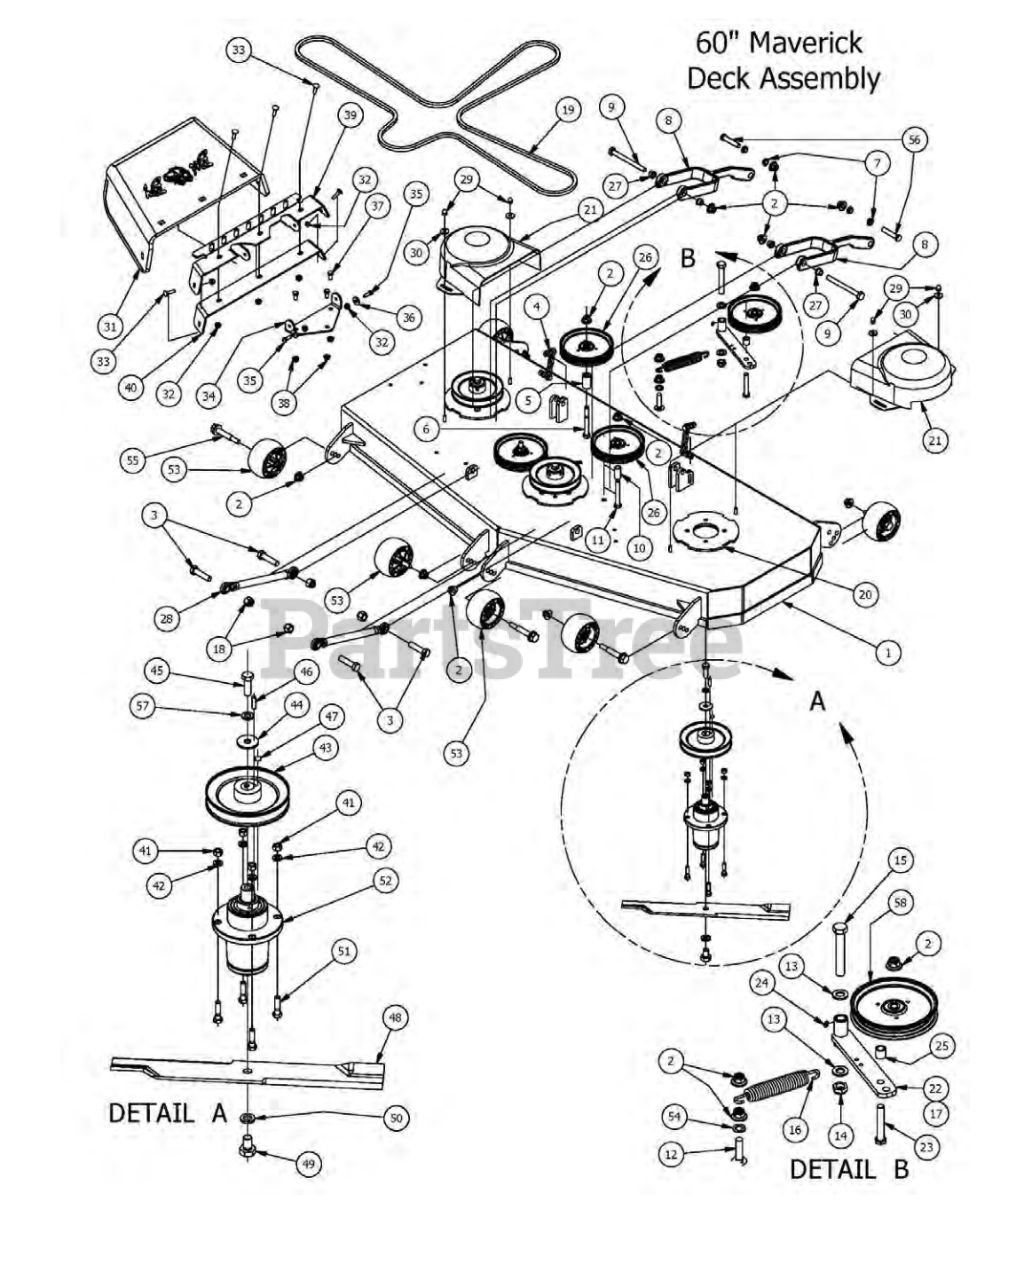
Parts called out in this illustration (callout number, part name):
1	60" ZT/Maverick Deck
2	1/2-13 Nylon Flange Nut
3	5/8" x 2 1/2" Grade 5 Hex Bolt (Coarse)
4	6 Link Chain assembly
5	13/4" Pulley Spacer
6	1/2" x 4" Bolt (Grade 8)
7	Flange Bushing For Lower Deck Arm
8	Deck Arm Assembly
9	1/2" x 5 1/2" Bolt
10	502 ID X.750 OD X 1.500 Long Spacer
11	1/2 x 3 1/2 Flange Bolt Grade 8
12	1/2 x 2" Carriage Bolt
13	630 ID Plastic Washer
14	5/8-11 Nylon Insert Jam Half Nut
15	5/8" x 4" Hex Bolt
16	2009 Deck/Pump Idler Spring
17	Deck Idler Assembly (Components 2,22,23,24,25,58)
18	5/8 Std NC Nylock Nut
19	60" ZT Deck Belt
20	Deck Spindle Support Plate
21	2014 ZT Pulley Cover
22	Deck Idler
23	1/2-13 x GR 5 Hex Bolt Zinc
24	1/4" Press in Grease Fitting
25	Spacer 3/4 OD x 1/2 ID x 314 Length
26	5-3/4 Idler Pulley
27	Flange Bushing For Upper Deck Arm
28	Tumbuckle (Top Link)
29	Acorn nut-pulley Cover
30	360 ID Plastic Washer-Black
31	Rubber Discharge Chute
32	5/16" Nylon Flange Nut
33	5/16" x 1 1/4" Carriage Bolt
34	Discharge Chute Hanger (Deck Mounted)
35	5/16" x 1" Bolt
36	360 ID Plastic Washer
37	3/8" x 3/4" Hex Bolt
38	3/8" Flange Nut
39	60" Discharge Chute Upper Hanger
40	60" Lower Hanger
41	3/8" Hex Nut
42	3/8" Lock Washer
43	6 1/4" Drive Pulley
44	1/2 Belleville Washer
45	1/2"-20 x 1 1/2 - Grade 5 Fine Thread Bolt
46	1/4" x 1" Key
47	5/16 Set Screw
48	60 Inch Fusion Blade
49	5/8" x 1 1/2" Grade 8 Hex Bolt (Fine)
50	5/8" Lock Washer
51	3/8" x 1 1/2" Hex Bolt
52	Spindle Assembly
53	Anti-Scalp Rollers
54	.517 Square Hole Round Washer
55	Deck Wheel Bolt
56	1/2" x 3" Hex Bolt
57	1/2" Lock Washer
58	5-3/4 Idler Pully
